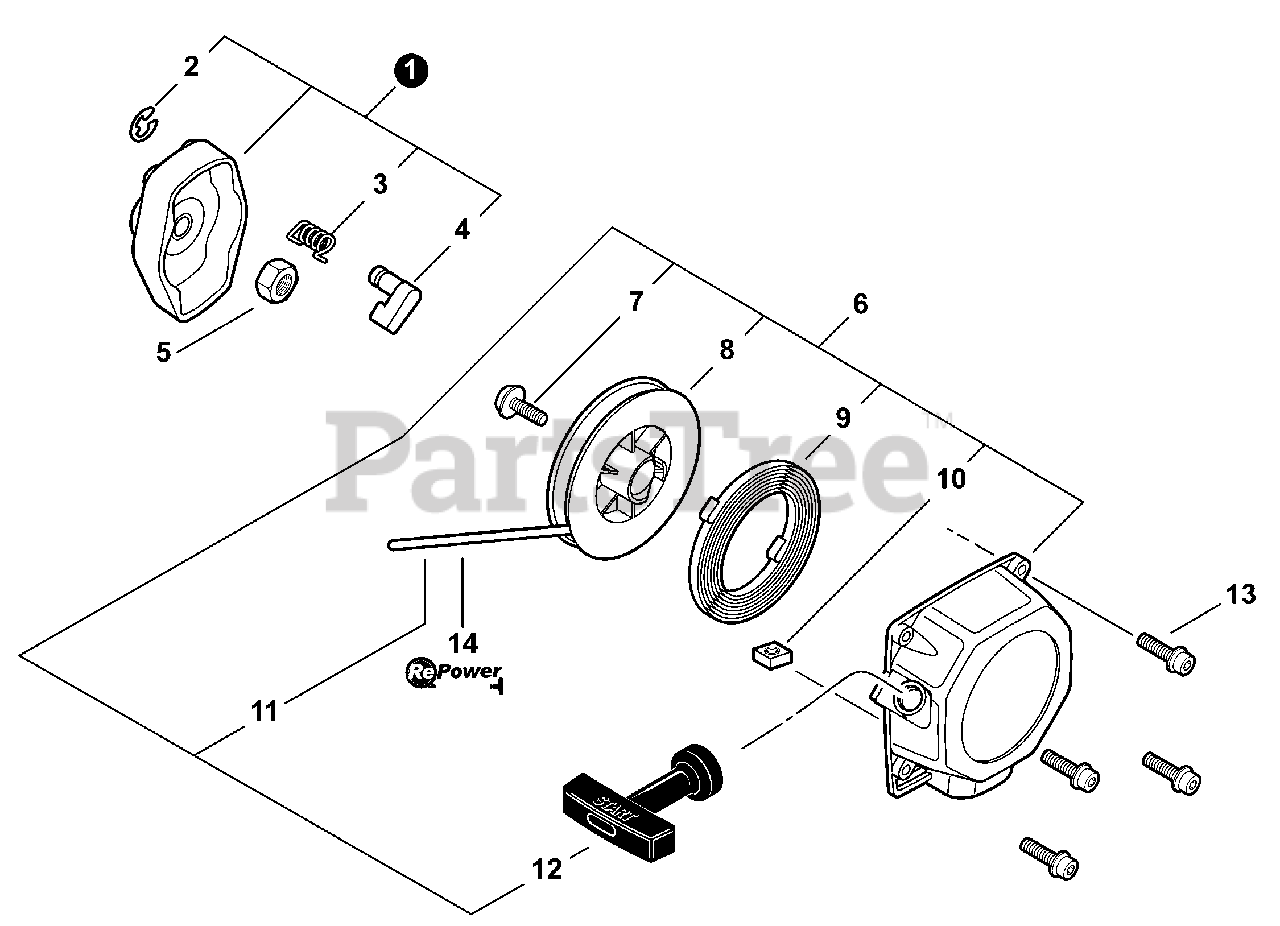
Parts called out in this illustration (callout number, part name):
1	PULLEY ASSY, STARTER
2	E-RING 4
3	SPRING, RETURN
4	PAWL, STARTER
5	NUT 8×1.25
6	STARTER, RECOIL
7	SCREW
8	REEL, ROPE
9	SPRING, RECOIL
10	NUT M5
11	ROPE, STARTER 3.5×900
12	GRIP, STARTER
13	SCREW 5×16
14	BULK STARTER ROPE - Ø 3.5 MM×61 M
